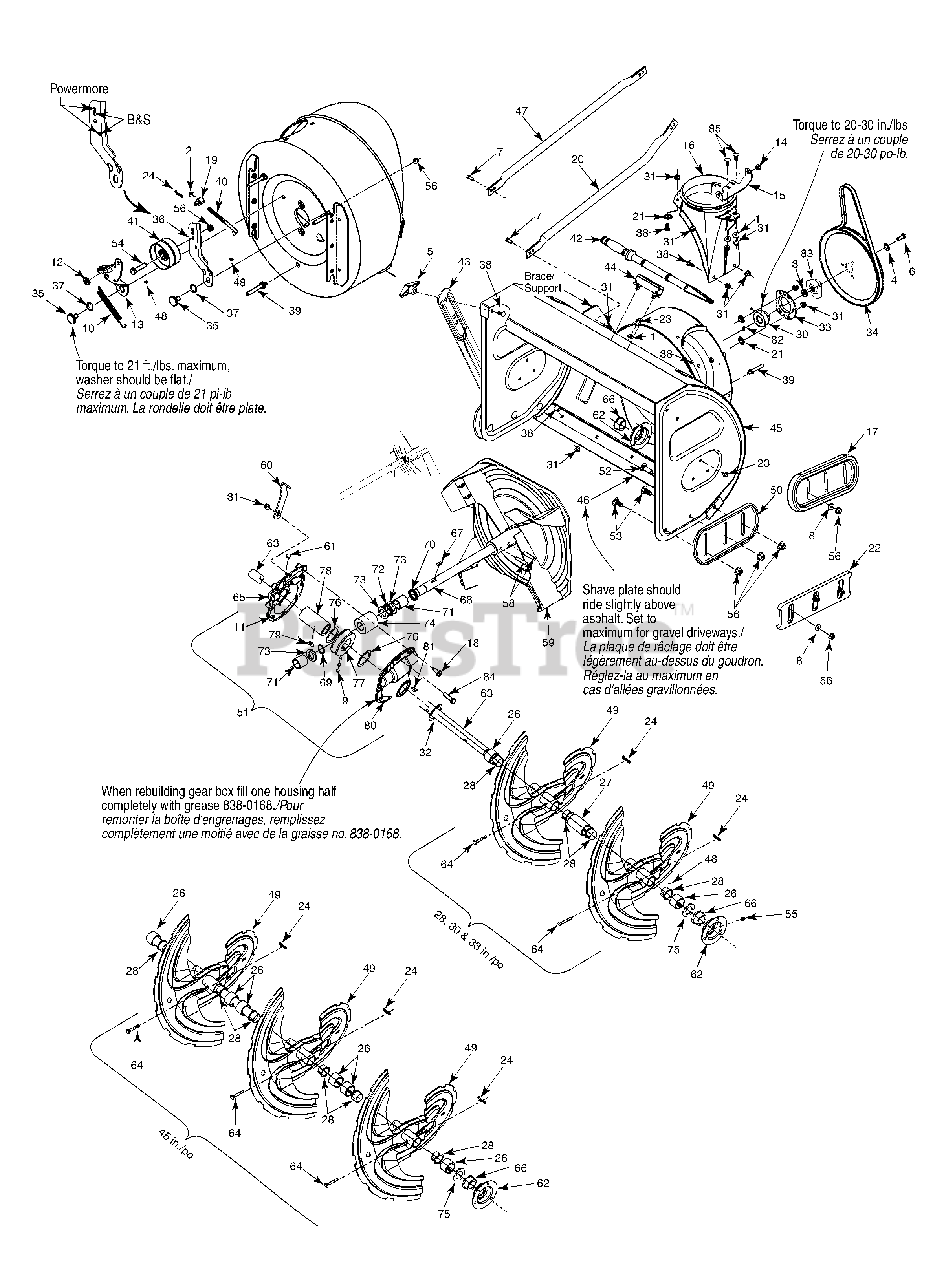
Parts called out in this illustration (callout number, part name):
1	Flat Washer .349 ID x .879 OD x .063
2	Hex Jam Nut 5/16-18 Gr. 5
3	Flat Washer .760 ID x 1.49 OD
4	Flat Washer .34 x 1.5 x .150
5	Handle Knob Assembly
6	Hex Screw 5/16-24 x .875 Gr. 8 Lock
7	Hex Hd Cap Scr. 5/16-18 x .75 Gr. 5
8	Flat Washer .385 x .870 x .092
9	Shell Alvania Grease (3 oz.)
10	Extension Spring .470 Dia. x 4.75
11	Ultra Grey Loctite #5699
12	Flat Washer .344 ID x .75 OD x .120
13	Brake Bracket Ass’y (900 Series)
14	Plastic Bushing .380 ID
16	Chute Adapter
17	Reversible Slide Shoe (Plastic)
18	Screw, 5/16-18 x .5
19	Adjustment Ferrule
20	Support Tubing RH (w/plastic panel)
20	Support Tubing LH (w/plastic panel)
21	Push-on Nut .25 diam
22	Deluxe Reversible Slide Shoe
23	Hex TT Screw 5/16-18 x .75
24	Bow Tie Cotter Pin
26	Spacer 1.5 x 1.0 ID x 1.0" Lg.
27	Spacer 1.5 x 1.0 ID x 2.5" Lg.
28	Flange Bushing 1.05 ID x 1.16 OD
30	Self-Aligning Bearing .875 ID
31	Hex Flg. L-Nut 5/16-18 Gr. F Nylon
32	Flat Washer 1.010 x 1.88 x .060
33	Bearing Housing
34	Pulley .5 ID x 10 OD
35	Shoulder Screw .625 Dia x .170
36	Auger Idler Bracket
37	Wave Washer .625 ID x .885 OD x .015
38	Carriage Bolt 5/16-18 x .75
39	Screw 5/16-18 x .43 (w/stud)
40	Auger Idler Rod
41	Flat Idler Pulley
42	Cleanout Tool
44	Cleanout Tool Mount
45	Auger Housing 28" Orange
45	Auger Housing 30" Orange
45	Auger Housing 33" Orange
46	Shave Plate 28" Orange
46	Shave Plate 30" Orange
46	Shave Plate 33" Orange
47	Support Tubing (w/steel panel)
48	Arctic Grease
49	LH Auger - Black
49	RH Auger - Black
51	Worm Gear Box Ass’y (w/o grease fitting)
51	Worm Gear Box Ass’y (w/ grease fitting)
52	Carriage Bolt 3/8-16 x 1.00" (w/steel shoe)
52	Carriage Bolt 3/8-16 x 1.25" (w/plastic shoe )
53	Carriage Bolt 3/8-16 x .75" (w/steel shoe)
53	Carriage Bolt 3/8-16 x 1.00" (w/plastic shoe)
54	Hex Hd. Cap Scr 3/8-16 x 1.75 Gr. 5
55	Grease Fitting
56	Hex Flange L-Nut 3/8-16 Gr. F Nylon
58	Spring Spirol Pin Heavy - 5/16 dia x 1.7
59	Blower Fan Ass’y Complete
60	Gear Housing Support Bracket
63	Auger Shaft 28"
63	Auger Shaft 30"
63	Auger Shaft 33"
64	Shear Pin 5/16-18 x 1.75
65	Gear Housing Half - RH
66	Flange Bearing
67	#9 HI-Pro Key 3/16 x 3/4 Dia HT
68	Auger Drive Shaft
69	Snap Ring for .875 dia. shaft
70	Oil seal for .875 ID Garlock (76 x 6133)
71	Sleeve Bearing .875 ID
72	Thrust Bearing .88 ID x 1.44 OD x .078
73	Flat Washer .88 ID x 1.4 OD x .125
74	Worm Gear LH Double Thread
76	Flat Washer 1.5 ID x 2.0 OD x .03
77	Worm Gear LH Double Thread (Bronze)
78	Worm Gear Shaft
79	#91 Woodruff Key 1/4 x 3/4 Dia.
80	Gear Housing Half LH
80	Gear Housing Half LH (w/grease fitting hole)
81	#91 Woodruff Key 1/4 x 3/4 Dia.
82	Low Temperature grease
83	Pulley Adapter .75 Dia. w/pins
84	Hex Hd. Cap Scr. 5/16-18 x 1.0 Gr. 5
85	Carriage Bolt 5/16-18 x 1.00" Lg
